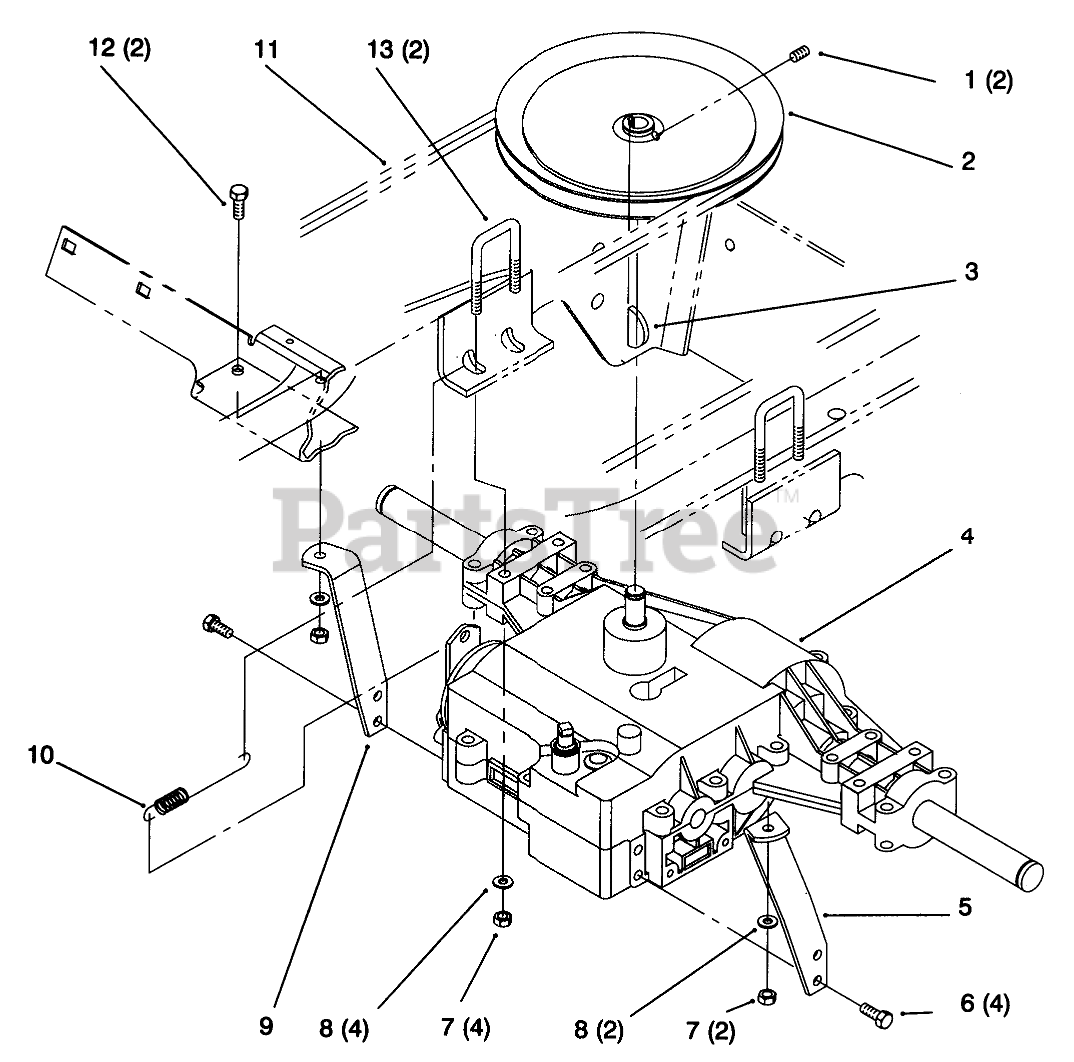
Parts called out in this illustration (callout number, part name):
1	Screw-Set (Only On: 72042, 72062)
2	Pulley (Only On: 72042, 72062)
3	Key (Only On: 72042, 72062)
4	Transaxle-Peerless 820 (Only On: 72042, 72062)
5	Strap-Torque LH (Only On: 72042, 72062)
6	Screw-TAP (Only On: 72042, 72062)
7	Nut-Lock (Only On: 72042, 72062)
8	Washer-Flat (Only On: 72042, 72062)
9	Strap-Torque RH (Only On: 72042, 72062)
10	Spring-Extension (Only On: 72042, 72062)
11	Belt-Gear (Only On: 72042, 72062)
12	Screw-HH (Only On: 72042, 72062)
13	U-Bolt (Only On: 72042, 72062)
